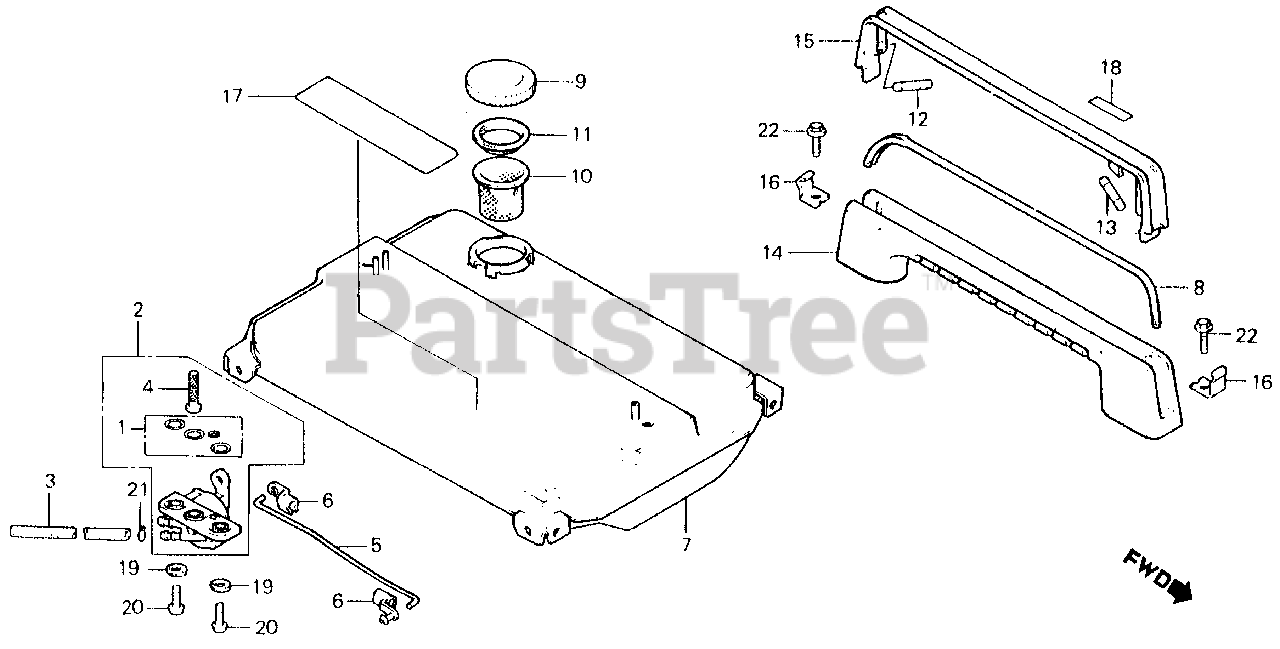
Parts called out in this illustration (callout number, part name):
1	GASKET SET, VALVE
2	PETCOCK ASSY.
3	TUBE, BREATHER PETCOCK (NOT AVAILABLE)
4	SCREEN, FUEL STRAINER
5	ROD, PETCOCK
6	JOINT, ROD
7	TANK, FUEL *NH44MS* (SPECIAL SILVER METALLIC)
8	TUBE, HANDLE BREATHER
9	CAP, TANK (NOT AVAILABLE)
10	FILTER, OIL
11	RUBBER, FILTER (NOT AVAILABLE)
14	HANDLE, CARRY
15	COVER, HANDLE (NOT AVAILABLE)
16	HOOK, HANDLE COVER
17	MARK A, CAUTION
19	GASKET, FIBER (6MM)
20	SCREW, PAN (6X20)
20	BOLT, FLANGE (6X20)
21	CLIP, TUBE (B8)
22	BOLT, FLANGE (6X10)
